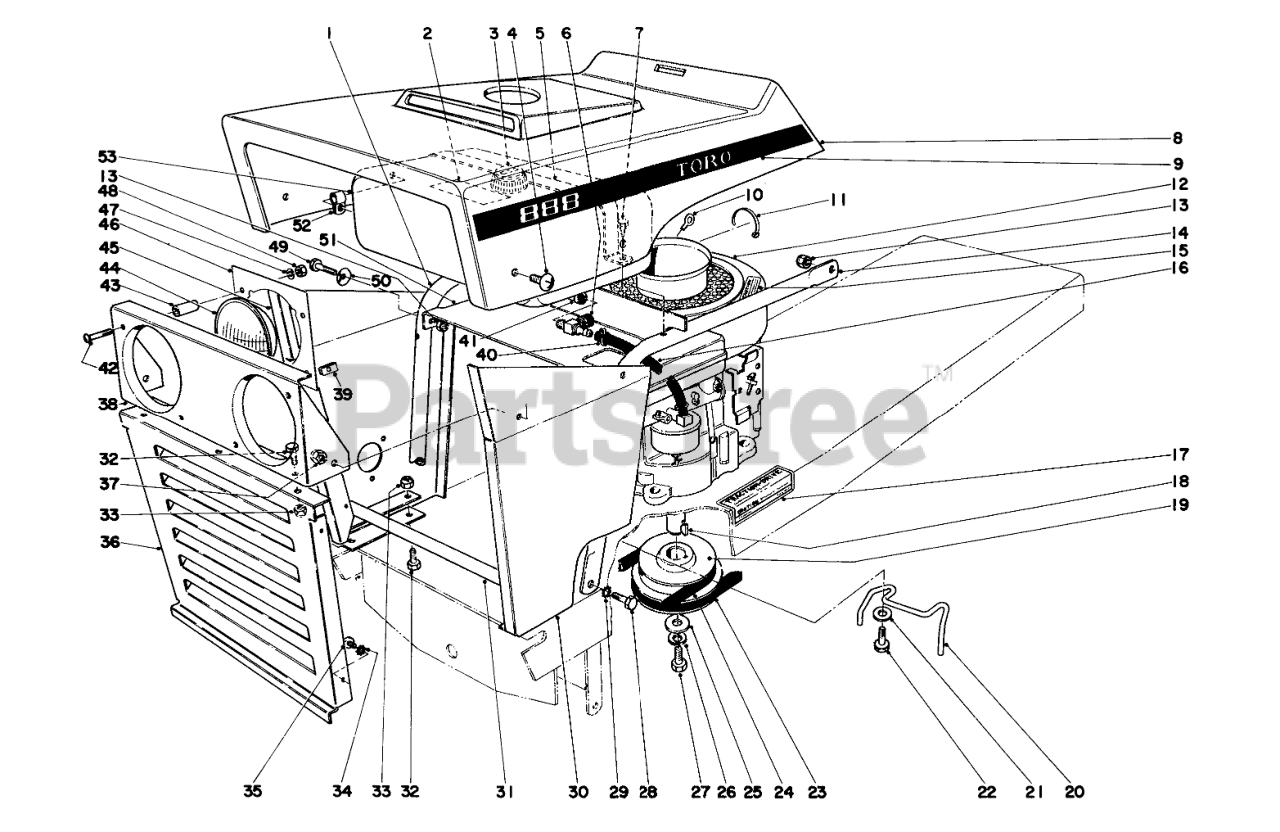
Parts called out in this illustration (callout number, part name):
1	Support-R.H.
2	Decal
3	Gas Cap
4	Round Head Screw
5	Hold Down
6	Shut Off Valve
7	SCREW-HWHTF
9	Decal Hood L.H.
11	Cable Tie
12	Engine
13	NUT-LOCK, CONE
14	Support Left
15	Caution Decal
17	Decal-Traction Drive
18	KEY-WOODRUFF
19	Pulley
20	Belt Guide
21	WASHER-FLAT
22	1/4-20X5/8 THDG SEMS
23	V-BELT
24	V BELT PTO
25	WASHER-FLAT
26	WASHER-LOCK
27	SCREW-HH
28	SCREW-HH
29	WASHER-LOCK
30	Skin Left Front
31	Hinge
32	SCREW-HH
33	NUT-LOCK, CONE
34	WASHER-LOCK, EXT
35	10-24 X 3/8 PAN HD SC
36	Grille
37	NUT-LOCK, CONE
38	Headlamp Panel
39	NUT-CLIP,U
40	Clamp
41	Elbow
43	Spacer
44	HEAD LAMP
45	Skin Right Front
46	Headlight Holder
47	WASHER-LOCK/SP
48	NUT-HEX
49	SCREW-HH
50	WASHER
51	Tray Gas Tank
52	R-CLAMP
53	GAS TANK
